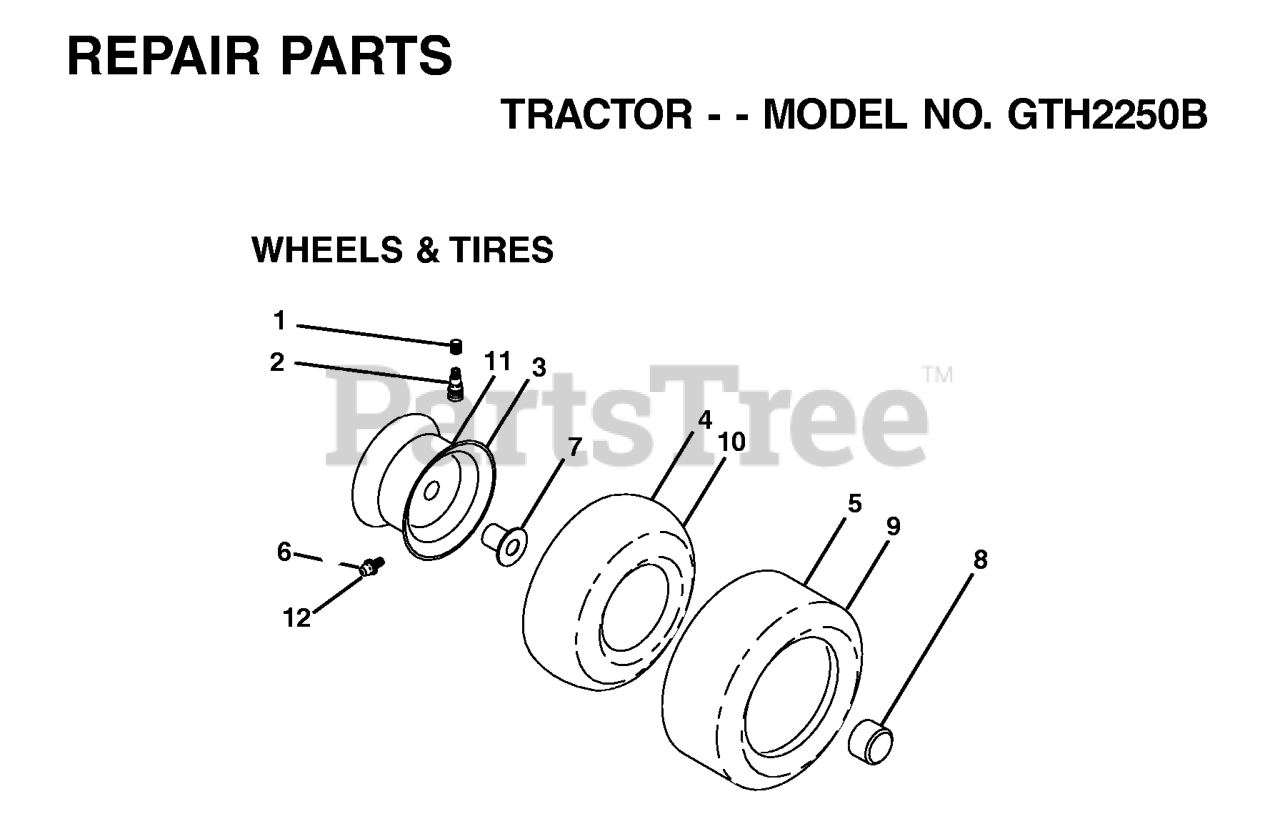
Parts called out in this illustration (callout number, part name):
2	VALVE STEM LT
3	RIM ASSEMBLY, FRONT
4	TUBE.16X6.5/7.5-8
5	TIRE HEAVY DUTY
6	FITTING LT
7	BEARING T
8	CAP, AXLE BLK
9	TIRE HEAVY DUTY
10	TUBE.23X9.5-12
11	RIM.ASM.12X7.REAR.SILVER
12	ZERK FITTING M
